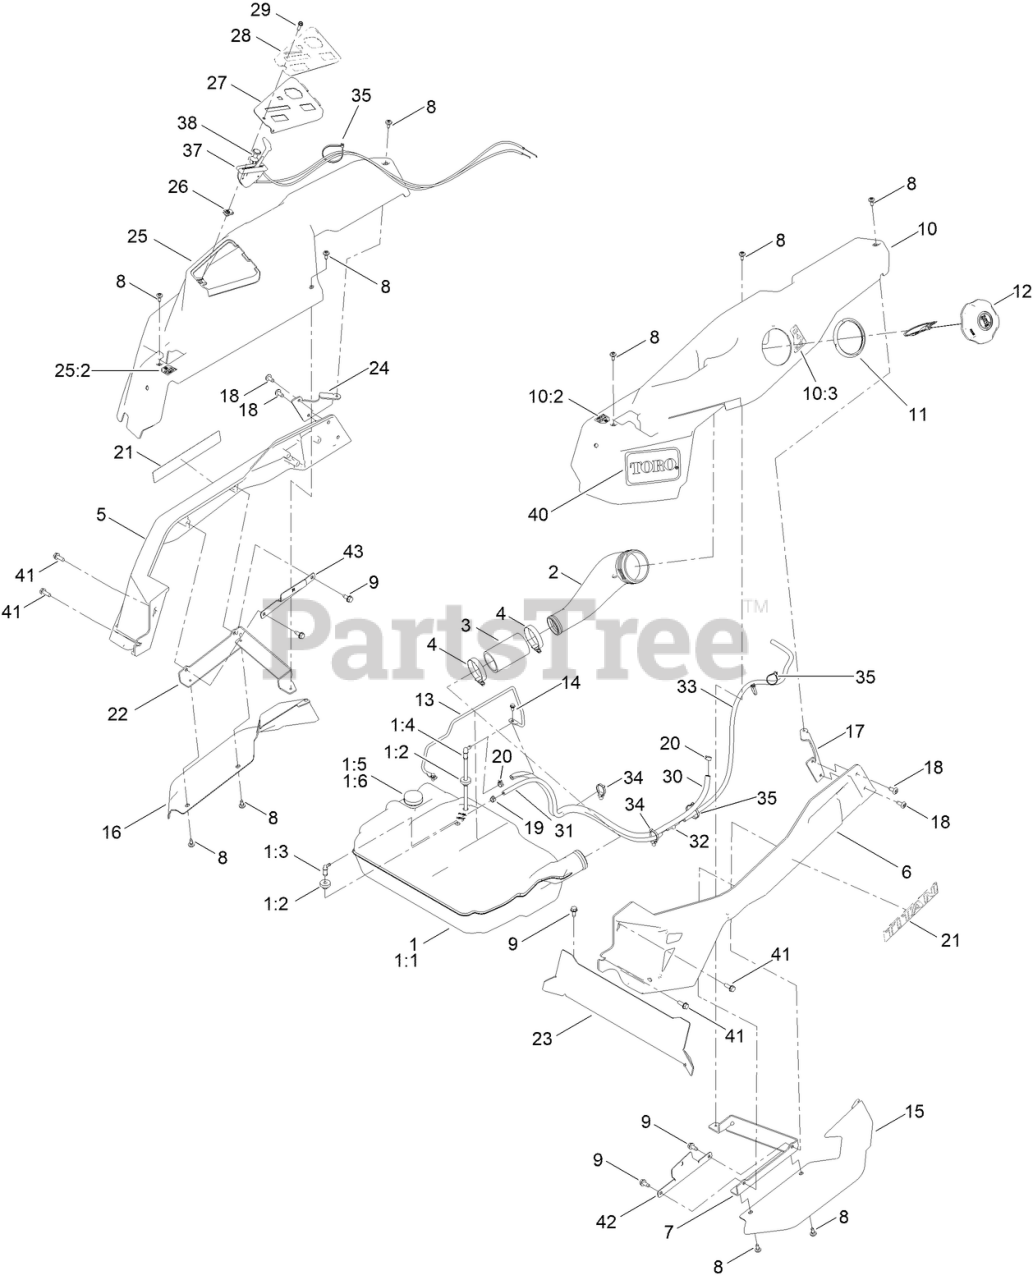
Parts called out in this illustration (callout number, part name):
1	TANK-FUEL, ASM
1:1	TANK-FUEL
1:2	BUSHING
1:3	FITTING-ELBOW 90
1:4	FITTING - PICKUP, FUEL
1:5	GROMMET-FUEL
1:6	REMOTE GAUGE ASM
2	NECK-FILLER, FUEL
3	HOSE-FILLER, FUEL
4	CLAMP-HOSE
5	CAST-TUBE, RH [RED]
6	CAST-TUBE, LH [RED]
7	MOUNT-POD BRACKET LH
8	SCREW-SHOULDER
9	SCREW-HWHTF
10	POD ASM - LH W/DECALS
10:2	DECAL-CONTROL LEVER, LH
10:3	DECAL-FUEL FILL
11	RING-RETAINING
12	CAP-FUEL, RATCHETING
13	ROD-HOLD DOWN
14	SCREW-HWH
15	FENDER-TIME CUTTER, LH
16	FENDER-TIME CUTTER, RH
17	BRACKET-REAR POD, LH
19	CLAMP-HOSE
20	CLAMP-HOSE
21	DECAL-TITAN
22	MOUNT-POD BRACKET RH
23	PLATE-KICK
24	MOUNT-POD BRACKET RH
25	POD ASM - RH W/DECALS
25:2	DECAL-CONTROL LEVER, RH
27	PANEL-CONTROL
28	DECAL - CONTROL PANEL
29	SCREW-HWHTF
30	HOSE-FUEL
31	HOSE-FUEL
32	ADAPTER ORIFICE
33	HOSE-LP
34	CLIP-TIE
35	TIE-CABLE
37	CABLE-THROTTLE
38	CABLE-CHOKE
40	DECAL - TORO LOGO
41	SCREW-TAPTITE
42	BRACKET-ALIGNMENT, POD LH
43	BRACKET- ALIGNMENT, POD RH
